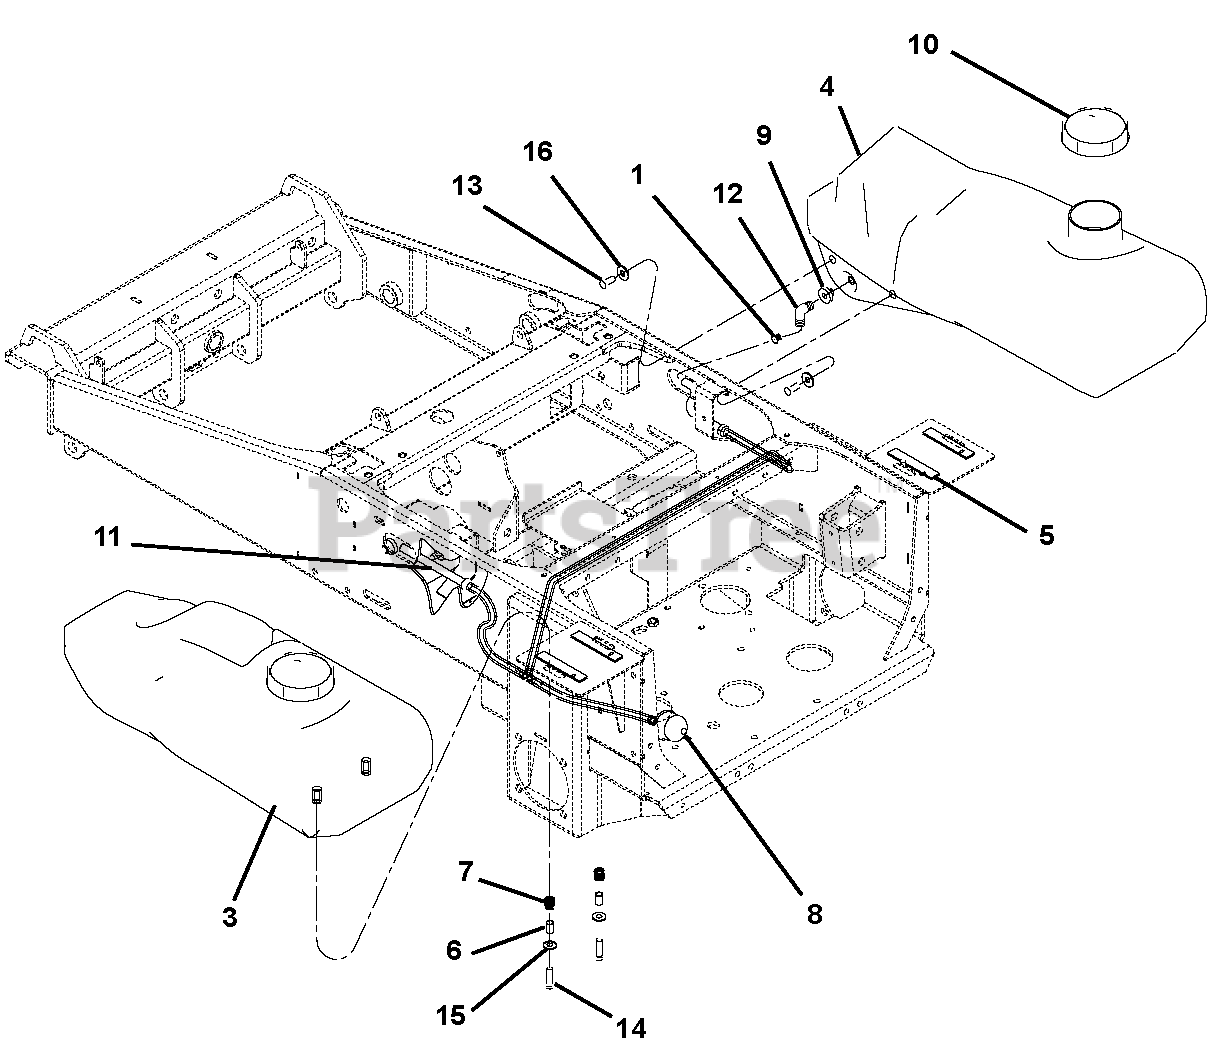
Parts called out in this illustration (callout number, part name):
1	Clamp, 1/2 Spring Hose
2	Frame
3	Tank, LH Midmount Blank w/Cap
4	Tank, RH Midmount Blank w/Cap
5	Foam, .125 x .750 x 4.00
6	Spacer, Gas Tank Attachment
7	Spring, Commpression .660 x .067 x .625
8	Fuel Filter
9	Grommet, Tank Fitting Rubber
10	Fuel Cap
11	Assembly, Fuel Line w/Checkvalves
12	Fitting, 90 Degree
13	Bolt, 3/8-16 x .750 Hex
14	Bolt, 3/8-16 x 1.25 Hex
15	Washer, Flat, Steel .38 x .875 x .083
16	Washer, .375 REG Flat
